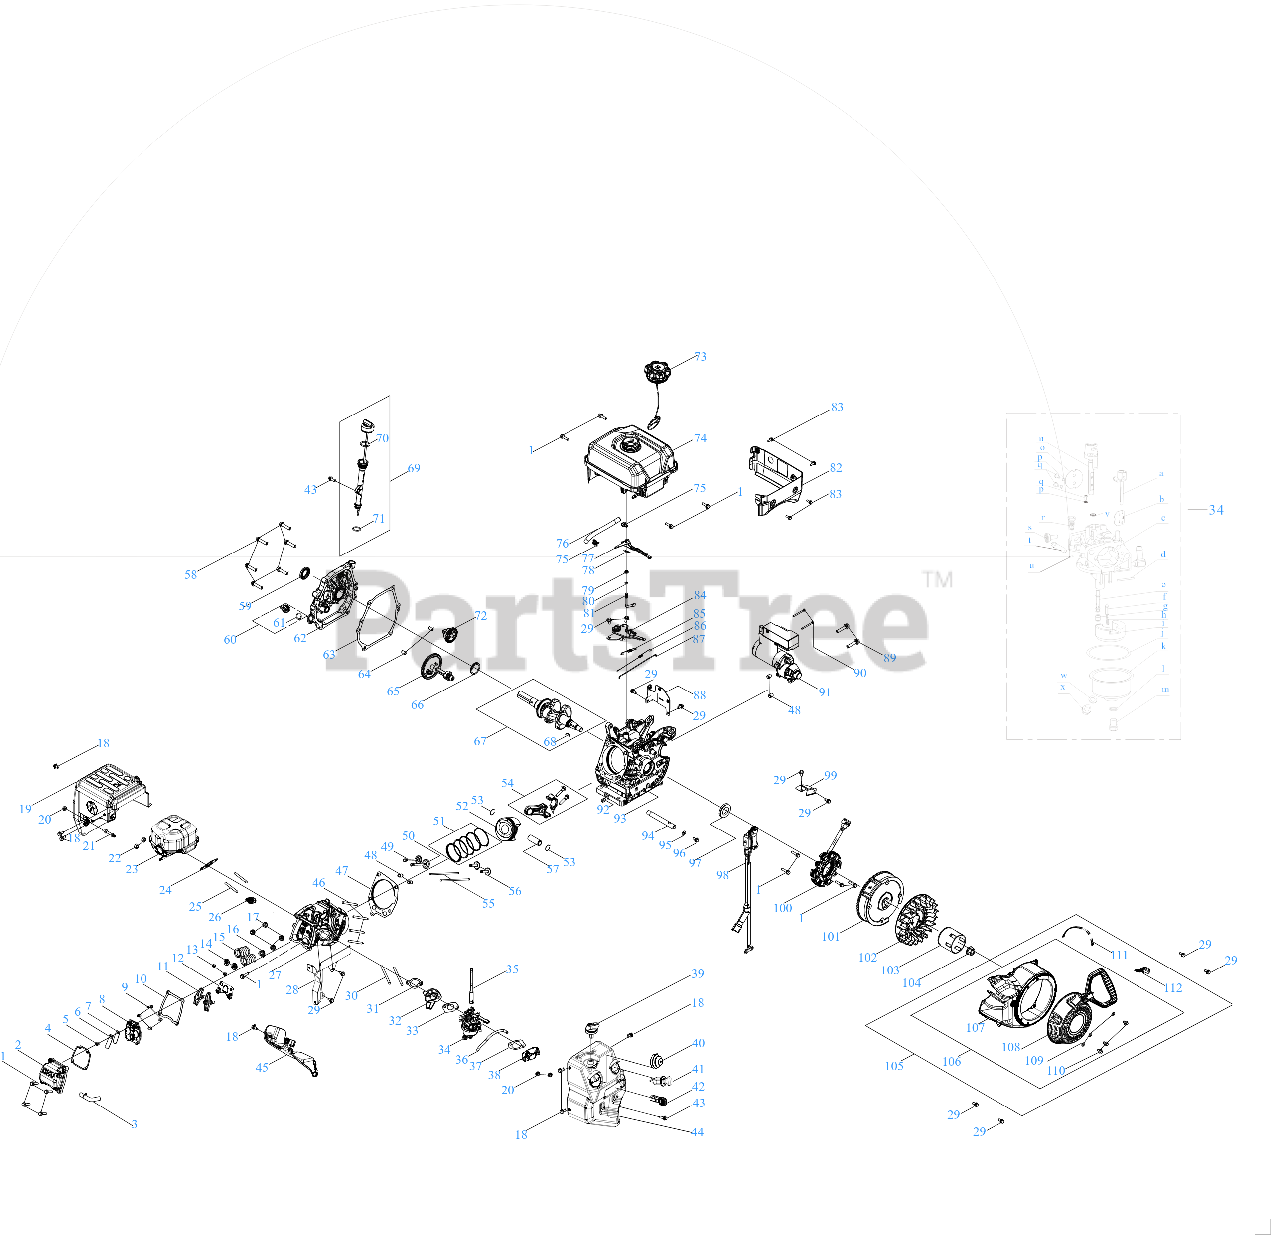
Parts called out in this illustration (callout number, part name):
1	BOLT M6-1 x 25 GR8.8
2	VALVE COVER
3	BREATHER HOSE
4	VALVE COVER GASKET
5	SCREW, M3×8
6	BREATHER PLATE
7	BREATHER VALVE
8	INNER VALVE COVER
9	SCREW, M5×12
10	VALVE COVER GASKET
11	ROCKER ARM
12	ROCKER ARM BASE
13	VALVE CLIP
14	VALVE SPRING SEAT
15	VALVE SPRING
16	INTAKE VALVE SEAL
17	NUT, M8
18	BOLT M6-1 x 14 GR8.8
19	MUFFLER GUARD
21	STUD, M6×55
24	MUFFLER GASKET
26	SPARK PLUG
27	CYLINDER HEAD
28	SNOW GUARD
29	BOLT M6-1 x 12 GR8.8
30	STUD M6-1 x 98
31	INSULATOR GASKET
33	CARBURETOR GASKET
34	CARBURETOR
35	CHOKE LINKAGE
36	PRIMER HOSE
37	AIR FILTER GASKET
38	HEATER BOX
39	CHOKE KNOB SHAFT
41	ENGINE KEY SWITCH ASSEMBLY
42	THROTTLE CONTROL KNOB
43	BOLT M6-1 x 18 GR8.8
44	CONTROL PANEL
45	ENGINE SHROUD
46	STUD, M8×60
47	CYLINDER HEAD GASKET
49	INTAKE VALVE
50	EXHAUST VALVE
51	PISTON RING SET
53	PISTON PIN SNAP RING
54	CONNECTING ROD
56	TAPPET
57	PISTON PIN
58	BOLT, M8×35
59	OIL SEAL
61	O-RING 15.8 x 2.5
62	CRANKCASE COVER
63	CRANKCASE GASKET
66	THRUST WASHER
67	CRANKSHAFT
68	FLYWHEEL KEY
70	O-RING
72	GOVERNOR GEAR
75	HOSE CLAMP
77	GOVERNOR LEVER
78	COTTER PIN
79	GOVERNOR SEAL
81	GOVERNOR GEAR SHFT
82	FUEL TANK COVER
83	BOLT: M5 x 14
84	GOVERNOR GEAR BRACKET
85	GOVERNOR SPRING
86	IDLER SPRING
87	THROTTLE LINKAGE
88	DIPSTICK BRACKET
89	BOLT, M8×40
91	ELECTRIC STARTER
92	OIL PLUG 1/8 NPT
94	OIL DRAIN PIPE
95	WASHER
96	OIL DRAIN PLUG
98	IGNITION MODULE
99	WIRE BOARD
100	CHARGING COIL
102	COOLING FAN
103	STARTER CUP
104	FLYWHEEL NUT
105	RECOIL STARTER
106	STARTER ASSEMBLY
107	BLOWER HOUSING
108	RECOIL STARTER ASSEMBLY
109	RECOIL FLAT WASHER
110	BOLT M6 x 10
111	CABLE TIE - 3 x 150
112	IGNITION KEY
